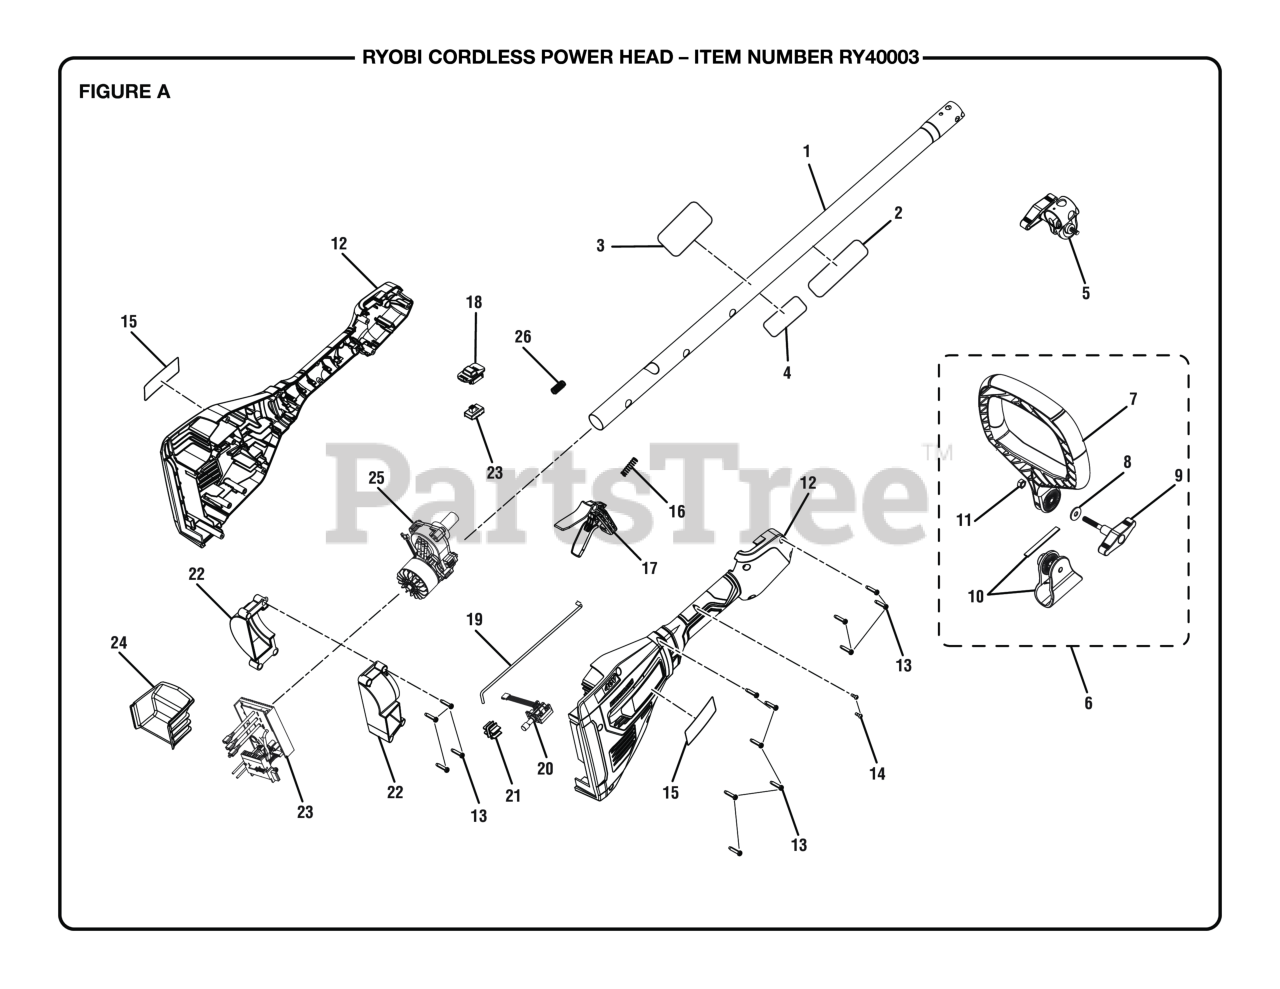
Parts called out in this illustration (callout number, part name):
1	Upper Boom Assembly
2	Warning Label (French/Spanish)
3	Warning Icon Label
4	Data Label
5	Boom Clamp Assembly
6	Front Handle Assembly
7	Lower Auxiliary Handle
8	Washer (ID6.4 x OD18 x 1.6t)
9	Knob Assembly
10	Auxiliary Handle Bracket Assembly
11	Lock Nut (M6)
12	Rear Handle Assembly
13	Screw (M4 x 18 mm, T15 Torx Pan Hd.)
14	Screw (M3 x 8 mm, Pan. Hd.)
15	Logo Label
16	Compression Spring (Trigger Lock)
17	Switch Trigger Assembly w/Lock-Out
18	Slide Switch Cover
20	Variable Speed Switch
21	Switch Cap
22	Motor Volute Assembly
23	Electric Controller and Switch Assembly
24	Bucket Housing
25	Motor and Gear Box Assembly
26	COMPRESSION SPRING
